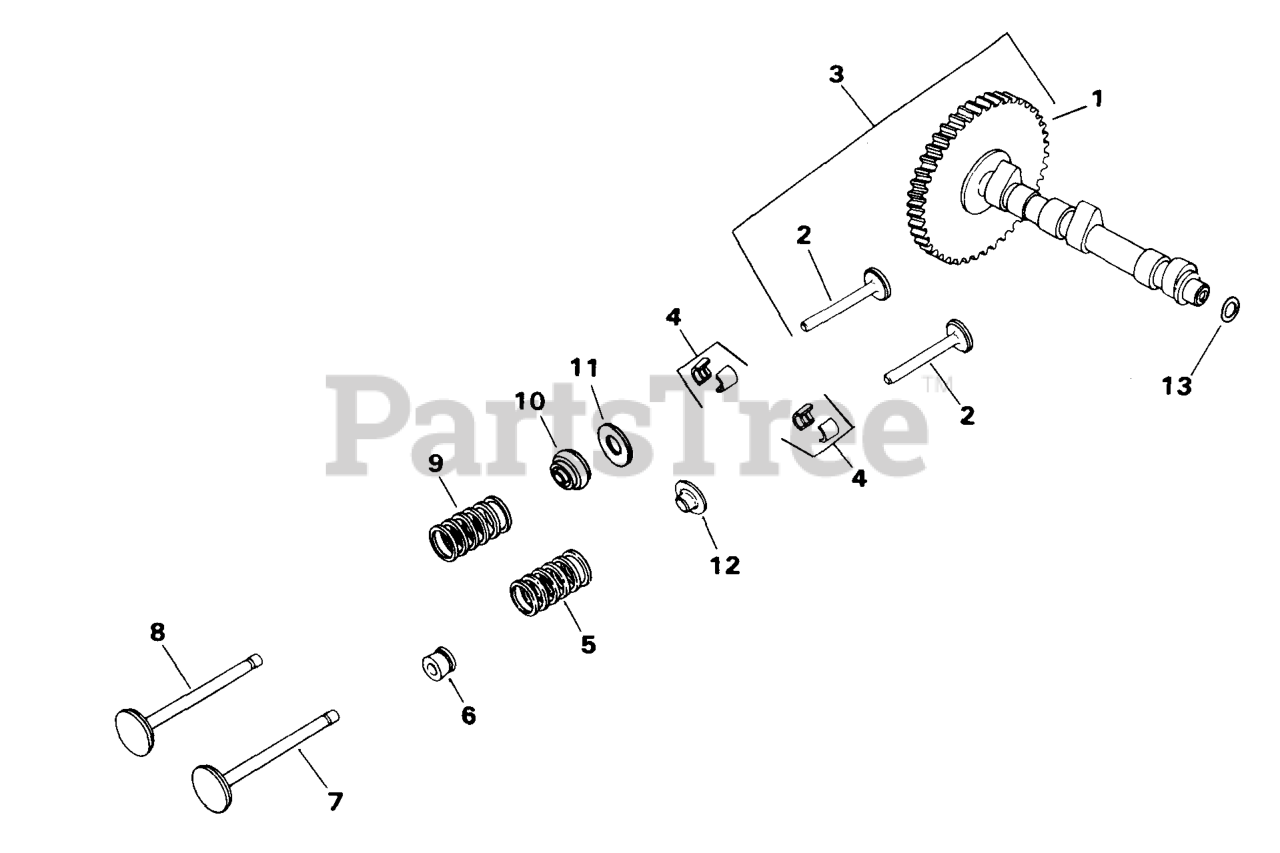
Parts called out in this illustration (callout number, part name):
3	Kit, Camshaft
4	Kit, Retainer
5	Spring, Intake Valve
6	Seal, Intake Valve Stem
7	Valve, Intake
8	Kit, Exhaust Valve
9	Spring, Exhaust Valve
10	Rotator, .03" Exhaust Valve
12	Retainer, Intake Valve Spring
